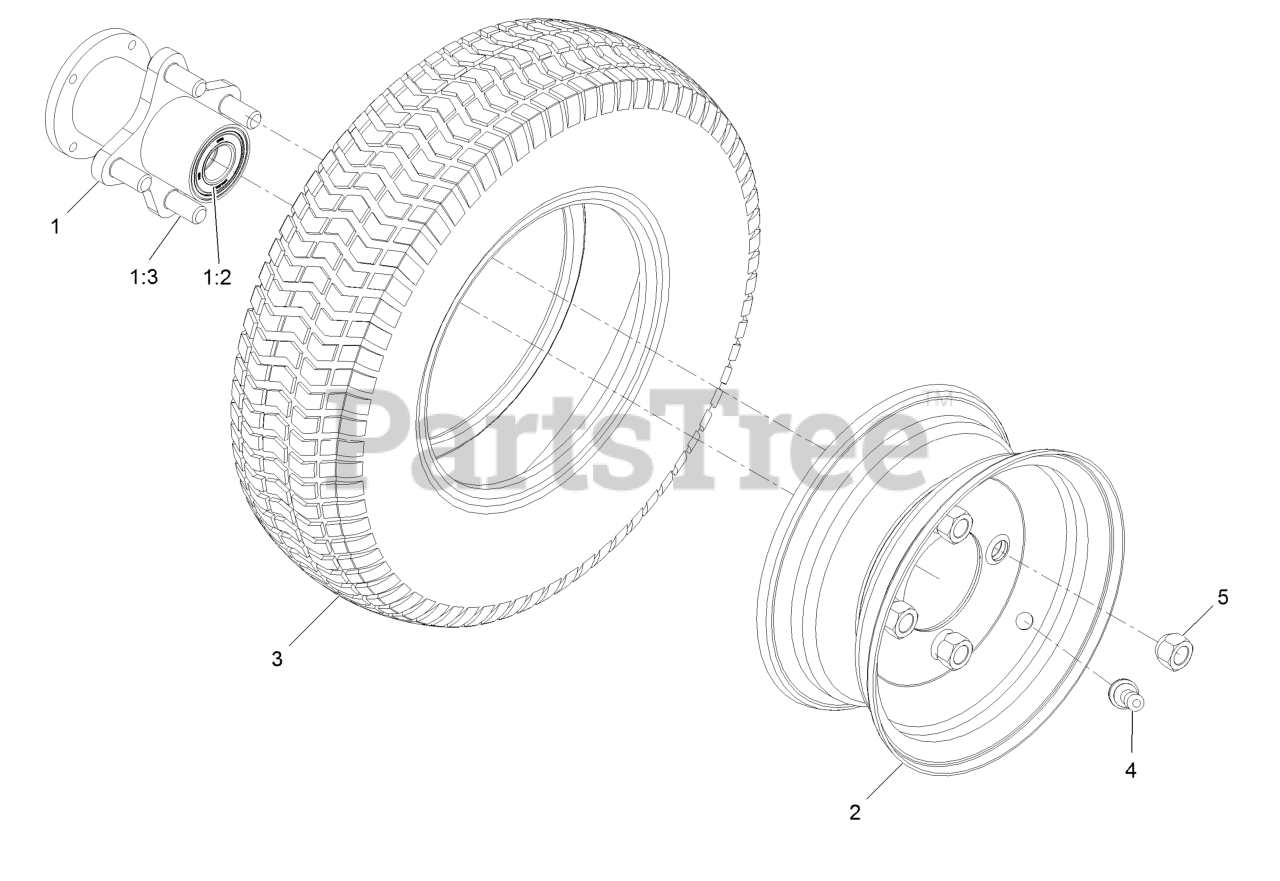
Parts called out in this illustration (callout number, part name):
1	Wheel Hub ASM
1:2	Bearing-Ball
1:3	Stud-Wheel
2	Rim
3	Tire
4	Stem-Valve
5	Nut-Lug 1/2-20
